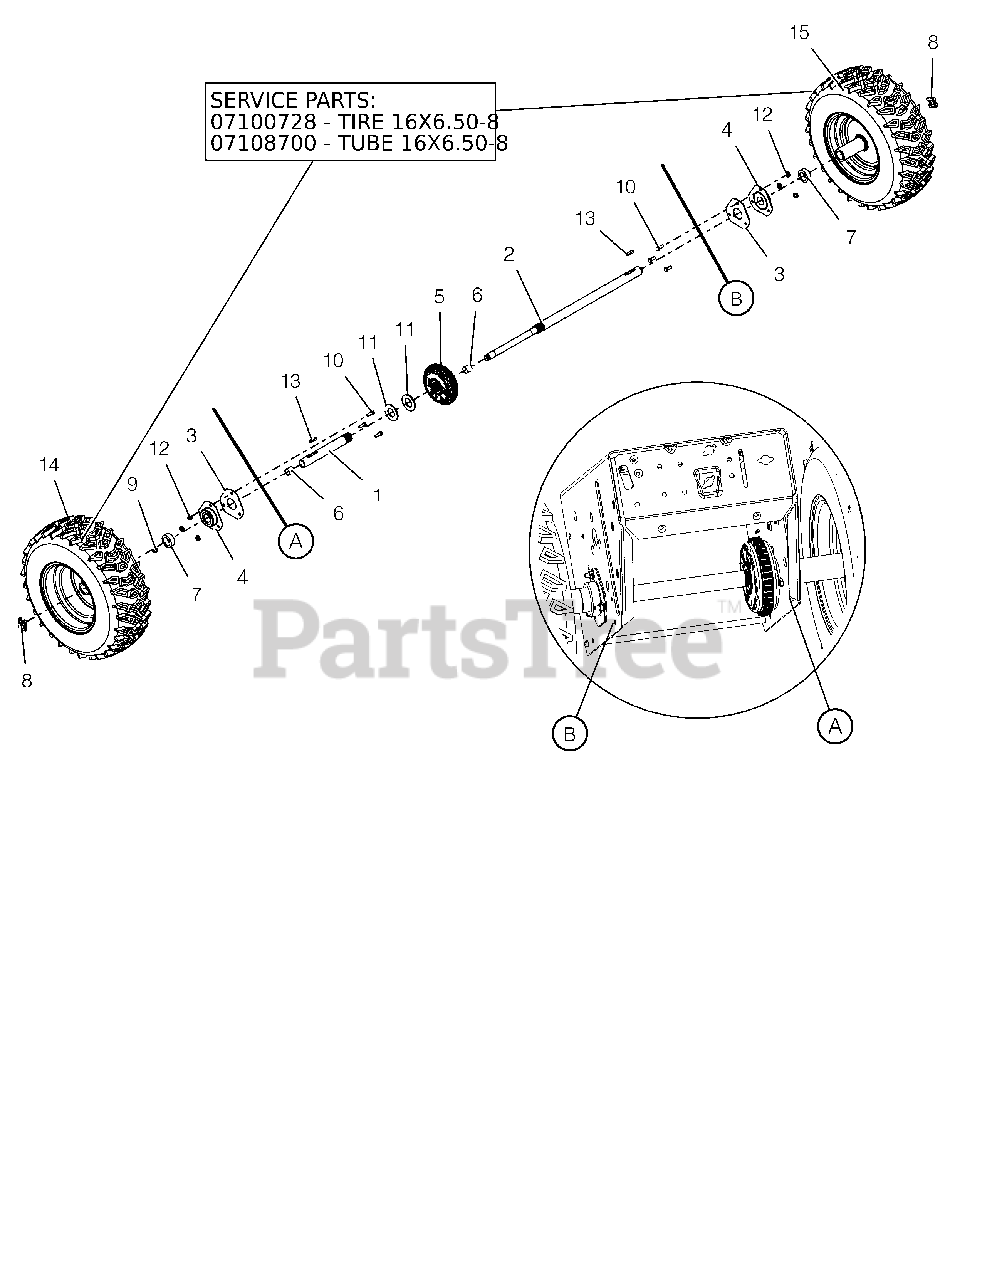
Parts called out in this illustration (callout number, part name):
1	AXLE, SHORT-AUTO W/BUSHINGS
2	AXLE, LONG-PRO AUTO DIFF
3	PLATE, BEARING SPACER
4	BRG-FLG 1.003/1.000 3 BOLT
5	DIFFERENTIAL, AUTOMATIC
6	BSHG-SLV .706X.764X.75 BRZ
7	SPACER, PRO AXLE BEARING
8	CLIP, SNAP .625 DIA
9	RG-RTNG-EXT .625X.042
10	@BLT-HEX .25-20X.75 GR5 YWZC
11	WSHR-FL-STL- 1.062X2.0X.134 YZ
12	NUT-LK-CTR-FLG .25-20 YWZC
13	KEY-RECT .25X.188X1.00
14	TIRE/WHEEL,RH 16X6.5-8 DIFF T2
14	TIRE, 16X6.50-8 K478
14	TUBE
15	TIRE/WHEEL,LH 16X6.5-8 DIFF T2
